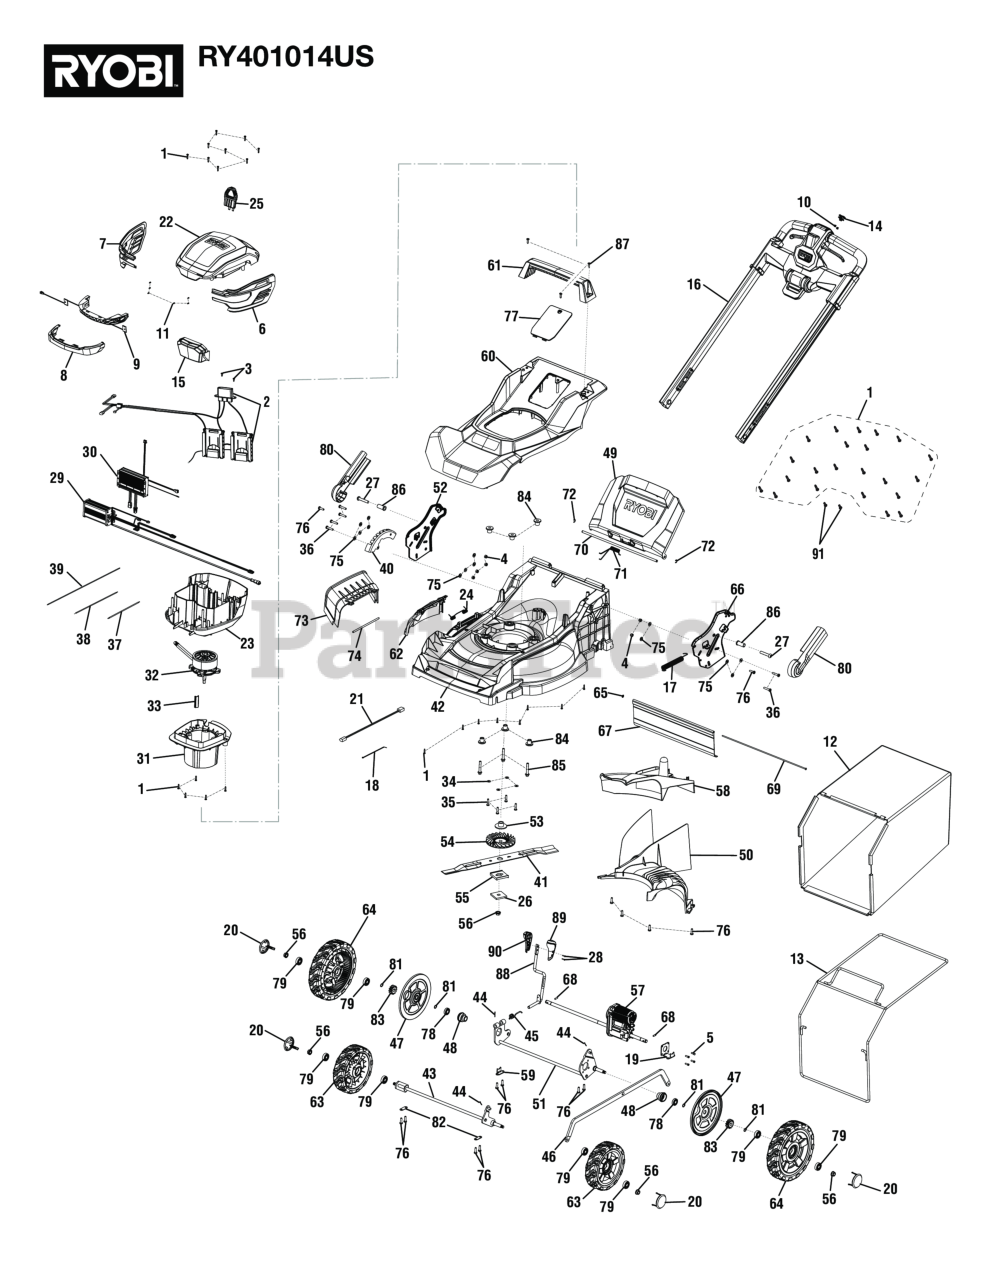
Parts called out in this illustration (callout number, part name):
1	Screw (M4 x 18 mm, T20 Torx Pan Hd.)
2	Key Base and Battery Foot Assembly
3	Screw (M4.2 x 12 mm, T20 Torx Pan Hd.)
4	Lock Nut (1/4-20 in.)
5	Screw (M5 x 14.5 mm)
6	Battery Housing Front Vents (Left)
7	Battery Housing Front Vents (Right)
8	LED Clear Window Lens
9	LED Circuit Board Assembly
11	Screw (M2.6 x 6 mm)
12	Grass Bag
13	Grass Bag Frame
14	Blade Button
15	Battery Housing Front Plug Cover
16	Handle Assembly
17	Compression Spring
18	NYLON CABLE TIE
19	Connecting Plate
20	Wheel Hub Cap
21	Inner Wire with Connector Between Transmission and Circuit Board Assembly
22	Battery Housing Assembly (Includes Labels)
23	Battery Housing Bottom
24	Mulch Cover Spring
25	Start Key Assembly
26	Blade Spacer Metal Plate
27	Screw (M10 x 48 mm, Hex. Recess Hd.)
28	Screw (M3 x 12 mm, Pan Hd.)
29	Self-Propelled Controller Assembly
30	Cutting Controller Assembly
31	Motor Bucket
33	Wire Harness Cover
34	Washer (ID6.2 x OD15 x 0.08t)
35	Bolt (M6 x 26 mm, Hex Hd.)
36	Screw (1/4-20UNC X 31.75 in., T30 Torx Pan Hd.)
37	Red Lead Wire (14 AWG, 215 mm)
38	Black Lead Wire (14 AWG,280 mm)
39	Electric Wire with Terminal (22 AWG)
40	Height Adjustment Bracket
42	Deck with Labels
43	Front Axle
44	Cotter PinÏ? (2.5)
45	Torsion Spring
47	Wheel Cover
48	Transmission Bearing Bushing
49	Rear Door
50	Discharge Baffle
51	Rear Axle
52	Handle Bracket (Right)
53	Motor Shaft Bushing
54	Motor Fan Blade Adapter
55	Plastic Blade Spacer
56	Blade Nut (M10 x 1.25, Hex Flange Hd.)
57	Transmission
58	Mulching Plug
59	Rear Axle Press Plate
60	Top Cover with Labels
62	Side Discharge Door
63	8 in. Wheel Assembly
64	10 in. Wheel Assembly
65	Retaining Ring
66	Handle Bracket (Left)
67	Trailing Shield
68	Gear Shaft
69	Trailing Shield Pin
70	Rear Door Axle
71	Rear Door Torsion Spring
72	Retaining Ring (E)
73	Side Charge Deflector
74	Hinge Rod
75	Washer (1/4 in.)
76	Screw (1/4-15 x 3/4 in., T30 Torx Pan Hd.)
77	Top Cover Door
78	Ball Bearing (OD28.6 x ID12.7 x 8)
79	Ball Bearing (ID12 x OD32 x 10 mm)
80	Hinge Cover
81	Retaining Ring
82	Front Axle Press Plate
83	Drive Gear
84	Engine Spacer
85	Screw (M8 x 50 mm, Hex Hd.)
86	Handle Bushing
87	Screw (10-14 x 19 mm, T25 Torx Truss Pan Hd. T.F.)
88	Height Adjustment
89	Height Adjustment Knob (Left)
90	Height Adjustment Knob (Right)
91	Screw (M4 x 10 mm, T20 Torx Pan Hd.)
